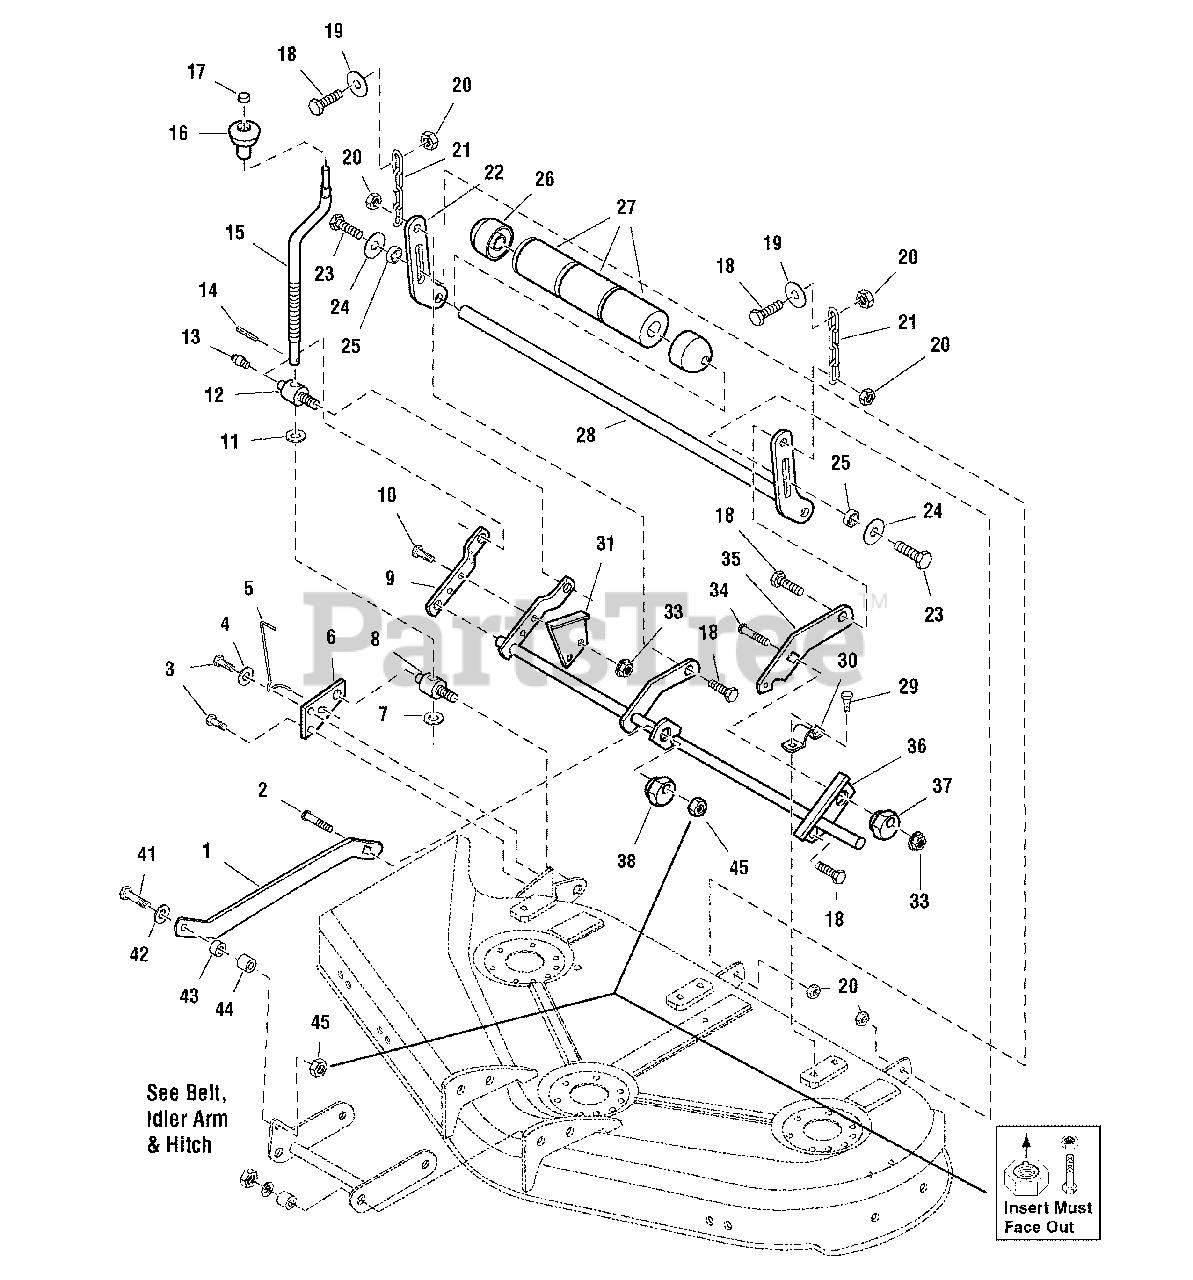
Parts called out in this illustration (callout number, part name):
2	CARRIAGE BOLT,3/8-16 x 1-1/2, Black
3	CAPSCREW, Hex Washer Head, Tap Tite, 5/16-18 x 1-1/4, Black
4	WASHER, 5/16, Black
5	ROD, Height of Cut
7	WASHER, Detent, Black
10	CAPSCREW, Hex Head, 5/16-18 x 1-1/4, Black
11	WASHER, 1/2, Black
13	FITTING, Lube
14	PIN, Spring
15	CRANK, Height Adjustment, Black
16	KNOB, Spinner
17	NUT, Push, 3/8, Black
18	CAPSCREW, Hex Head, 3/8-16 x 1-1/2, Black
19	WASHER, 3/8, Black
20	NUT, Hex Flange Lock, 3/8-16, Black
21	CHAIN, Link, 5-5/8 Long, 4 Links
22	BAR, Roller
23	CAPSCREW, Hex Head, 5/16-18 x 1-1/4, Black
24	WASHER, 5/16, Black
26	ROLLER, Rounded, 5/8 ID x 2-1/2 OD x 2" Long
27	ROLLER, 5/8 ID x 2-1/2 OD x 4" Long
28	SHAFT & BAR ASSEMBLY
29	CAPSCREW, Hex Washer Head, Tap Tite, 5/16-18 x 3/4, Black
30	STRAP
31	BRACKET, Height of Cut
33	NUT, Hex, 5/16-18, Black, Whiz Lock Flange
34	CARRIGE BOLT, 5/16-18 x 1-1/4
36	SHAFT ASSEMBLY
37	CAM, Eccentric
38	NUT, Hex Adjusting, .99 DIA .687
41	CAPSCREW, Hex Head, 3/8-16 x 1-3/4
42	WASHER
45	NUT, Hex, 3/8-16
